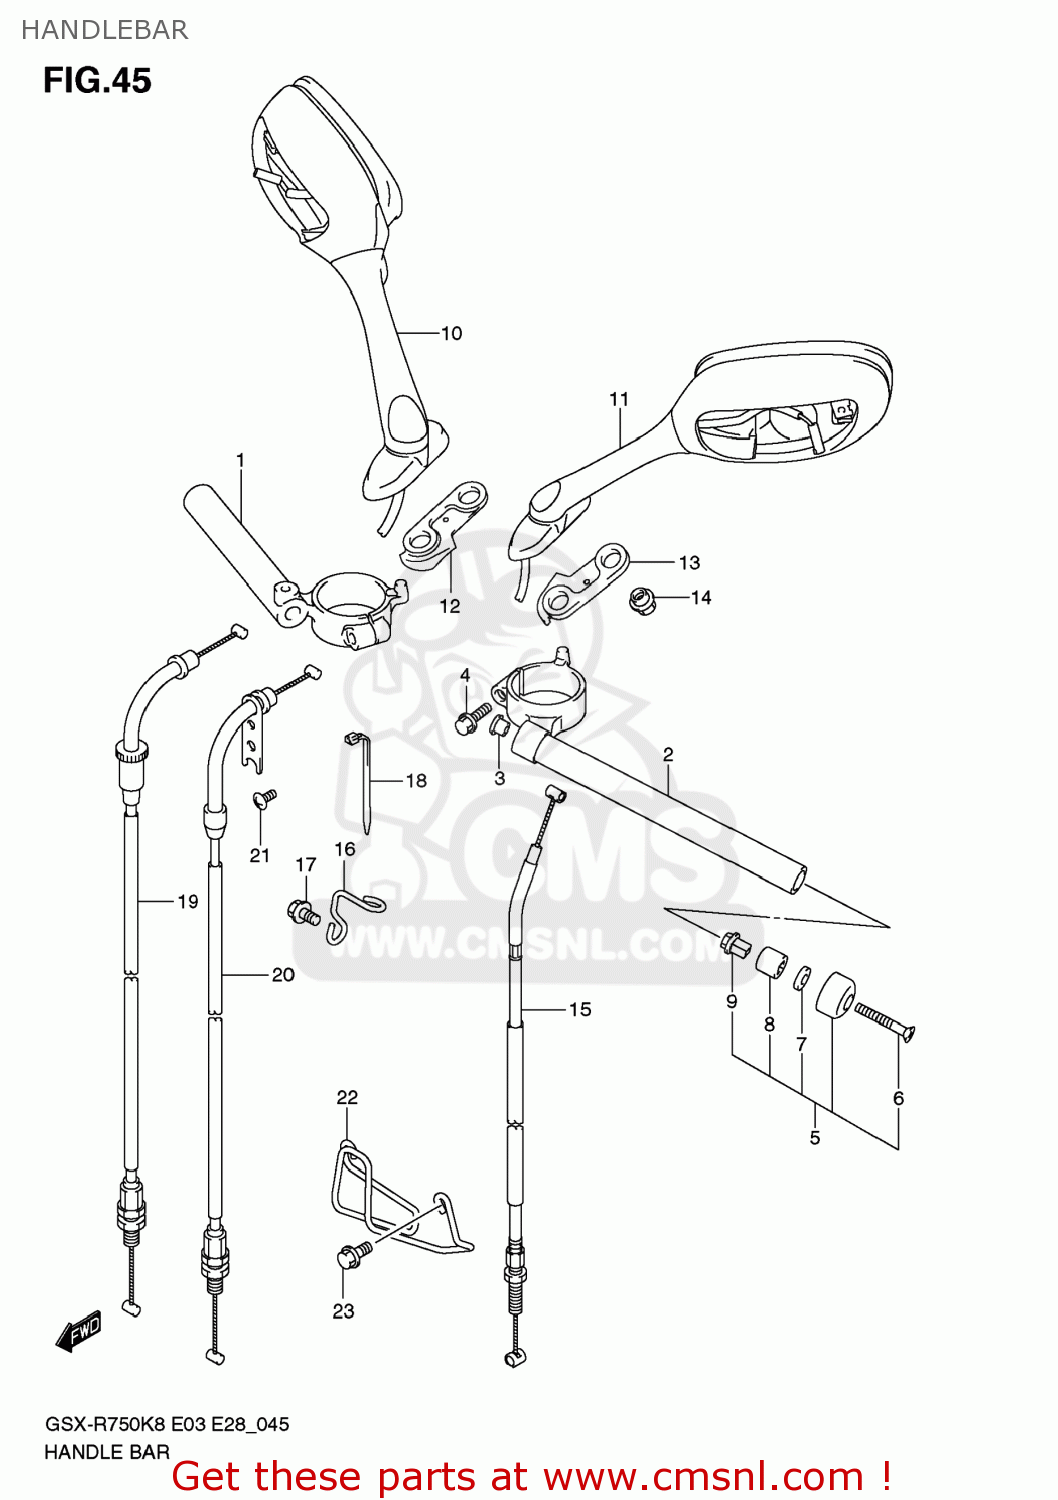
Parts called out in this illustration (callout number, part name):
1	HANDLEBAR,R
2	HANDLEBAR,L
3	CAP,HANDLEBAR
4	BOLT(8X32)
5	BALANCER SET,HANDLEBAR
6	SCREW
7	WASHER(6.5X16X4)
8	EXPANDER,HANDLE BALANCER
9	NUT,HANDLE BALANCER
10	MIRROR ASSY,RR VIEW,R
11	MIRROR ASSY,RR VIEW,L
12	CUSHION,RR VIEW MIRRROR,R
13	CUSHION,RR VIEW MIRRROR,L
14	NUT,RR VIEW MIRROR
15	CABLE ASSY,CLUTCH
16	GUIDE,CLUTCH CABLE
17	BOLT
18	CLAMP(L:154)
19	CABLE ASSY,THROTTLE NO.1
20	CABLE ASSY,THROTTLE NO.2
21	SCREW(5X10)
22	GUIDE,THROTTLE CABLE NO.2
23	BOLT
